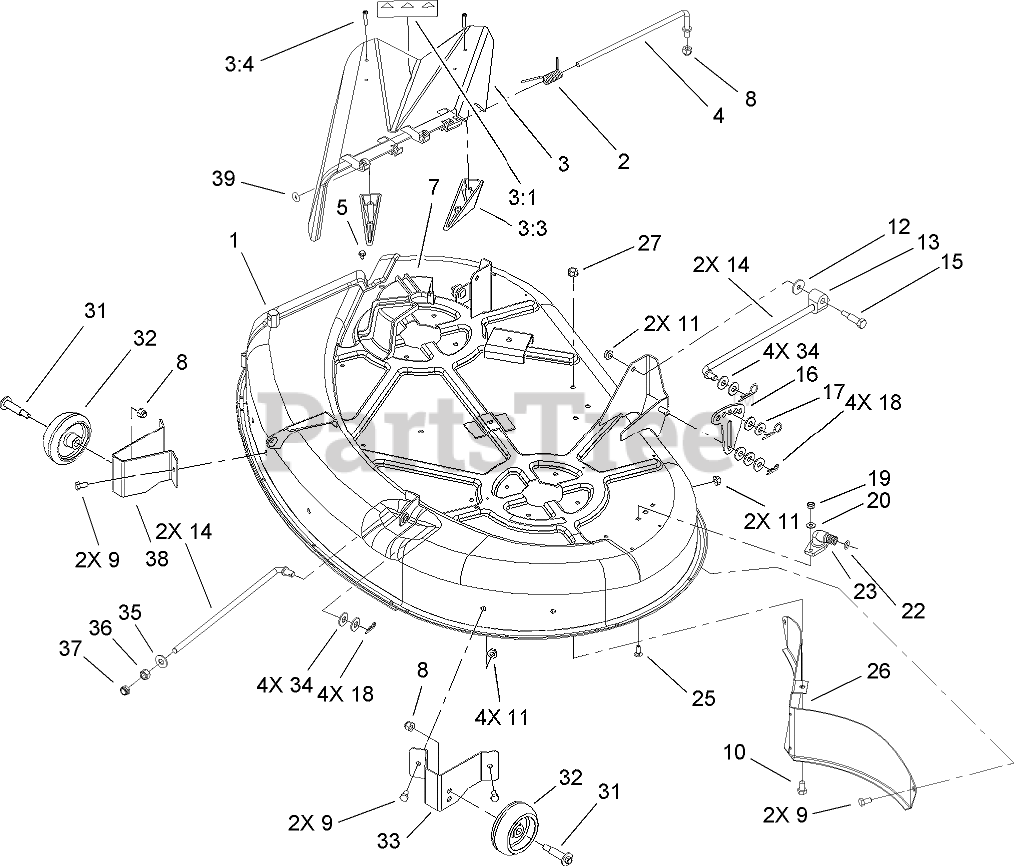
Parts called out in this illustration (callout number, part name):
1	42 INCH DECK ASM
2	SPRING
3	DEFLECTOR ASM
3:1	DECAL-DANGER
3:3	KICKER
3:4	SCREW-PPH
4	ROD-PIVOT
5	SCREW-HWHTF
7	GUIDE-BELT, RH
8	NUT-LOCK, NI
9	SCREW-HH
10	SCREW-HH
11	NUT-HF
12	WASHER-PIVOT
13	TRUNNION-HOC
14	ROD-HANGER
15	SCREW-SHOULDER, HH
16	LINK-ADJUSTING, HOC
17	WASHER-HARDENED
18	PIN-HAIR
19	NUT-LOCK, NI
20	WASHER-FLAT
22	O-RING
23	FITTING-WASHOUT
25	BOLT-CARR
26	BAFFLE-REAR
27	NUT-HF
31	SCREW-SHOULDER, HWH
32	WHEEL-GAGE
33	BRACKET-GAGE WHEEL, FRONT (LH)
34	WASHER-FLAT
35	WASHER-FLAT
36	NUT-HEX
37	NUT-LOCK, NI
38	BRACKET-GAGE WHEEL, FRONT (RH)
39	O-RING
